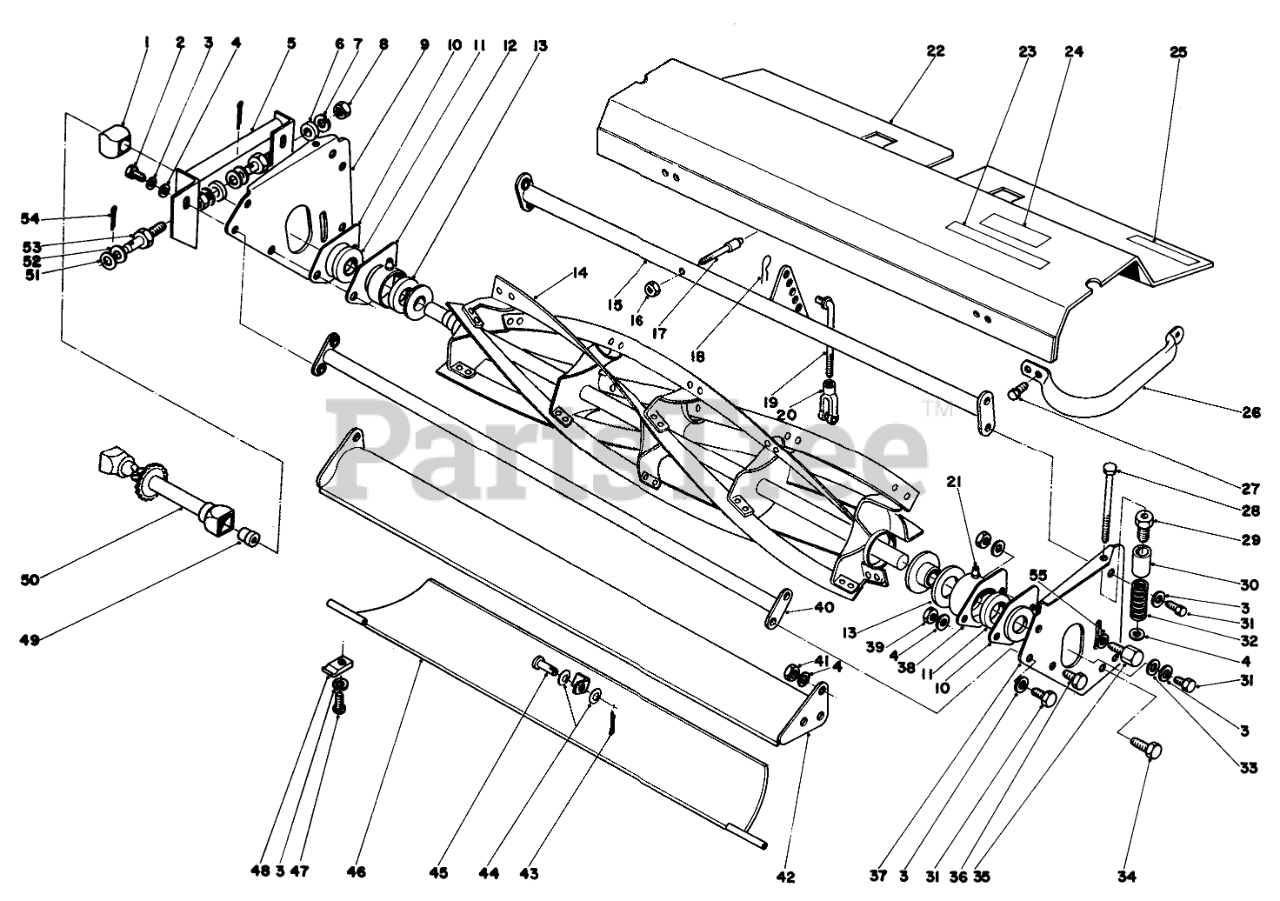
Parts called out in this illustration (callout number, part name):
1	DRIVE BALL
2	SCREW-HH
3	WASHER-LOCK, INTERNAL
4	WASHER-PLAIN
5	Hitch Left Hand
6	SPHERICAL SPACER
7	WASHER-LOCK
8	NUT-HEX
9	Side Plate
10	Cup-Bearing
11	.6693 RP BALL BEARING
12	Cup Bearing
13	1 X .250 OIL SEAL
14	Reel Assy.-Left
15	Tube, Reel
16	NUT-KEPS
17	Pin-Link
18	PIN-COTTER
19	Rod Adjusting
20	YOKE
21	FITTING-GREASE
22	Shield Grass
23	Decal
24	Decal
25	WARNING DECAL
26	Guard-Reel
27	10-16 X 3/8 THDG SCREW
28	Screw-Adjusting
29	Bolt-Adjusting
30	ADJUSTMENT BLOCK
31	SCREW-HH
32	SPRING-COMPRESSION
33	WASHER-FLAT
34	SCREW-HH
35	REEL BEARING SCREW
36	BEARING CUP BOLT
37	Side Plate
38	Cup Bearing
39	NUT-LOCK
40	Tube-Reel
41	NUT-HEX
42	BEDKNIFE WA
43	PIN-COTTER
44	WASHER-SPRING
45	PIN-CLEVIS
48	CLIP-SKID
49	REEL DRIVE PAD
50	Shaft-Reel Drive
51	COLLAR
52	9/16ID X 032 WASHER
53	PIVOT STUD
54	PIN-COTTER
55	WASHER
